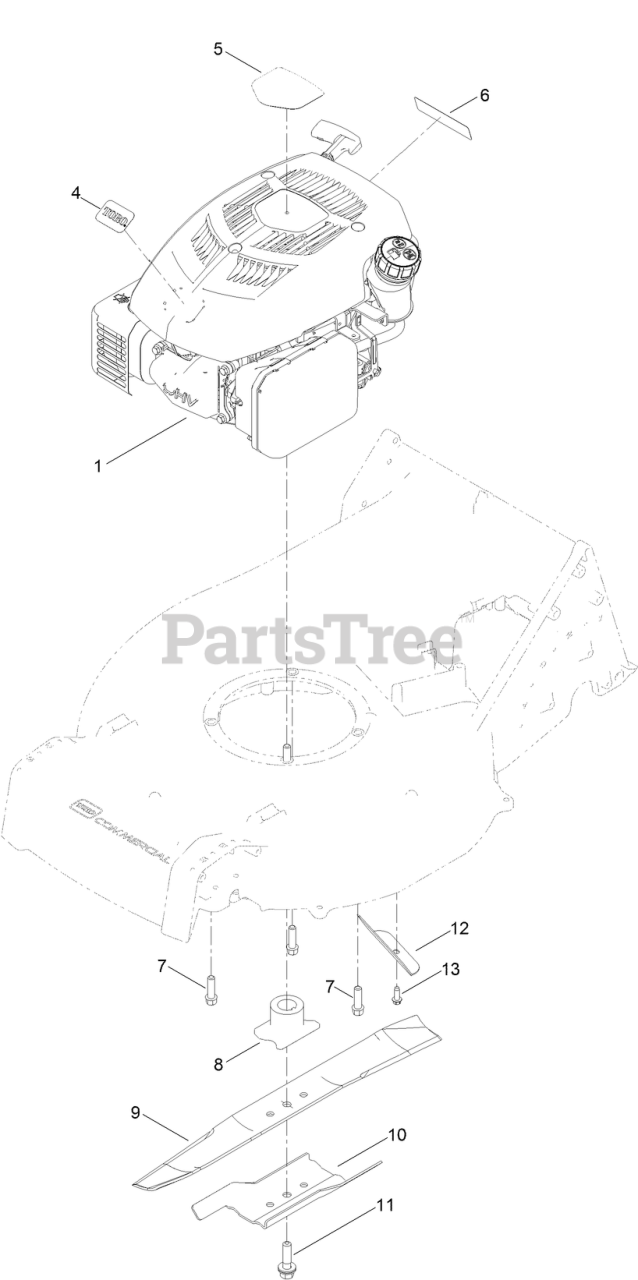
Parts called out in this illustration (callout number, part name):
1	ENGINE-1P65F-2
5	DECAL-SHROUD
6	DECAL-ARRESTOR, SPARK
7	SCREW-TAPTITE
8	DRIVER-BLADE
9	BLADE-21IN, RECYCLING
10	ACCELERATOR-BLADE
11	BOLT-BLADE
12	SHIELD-GRASS
13	SCREW-HWHTF
